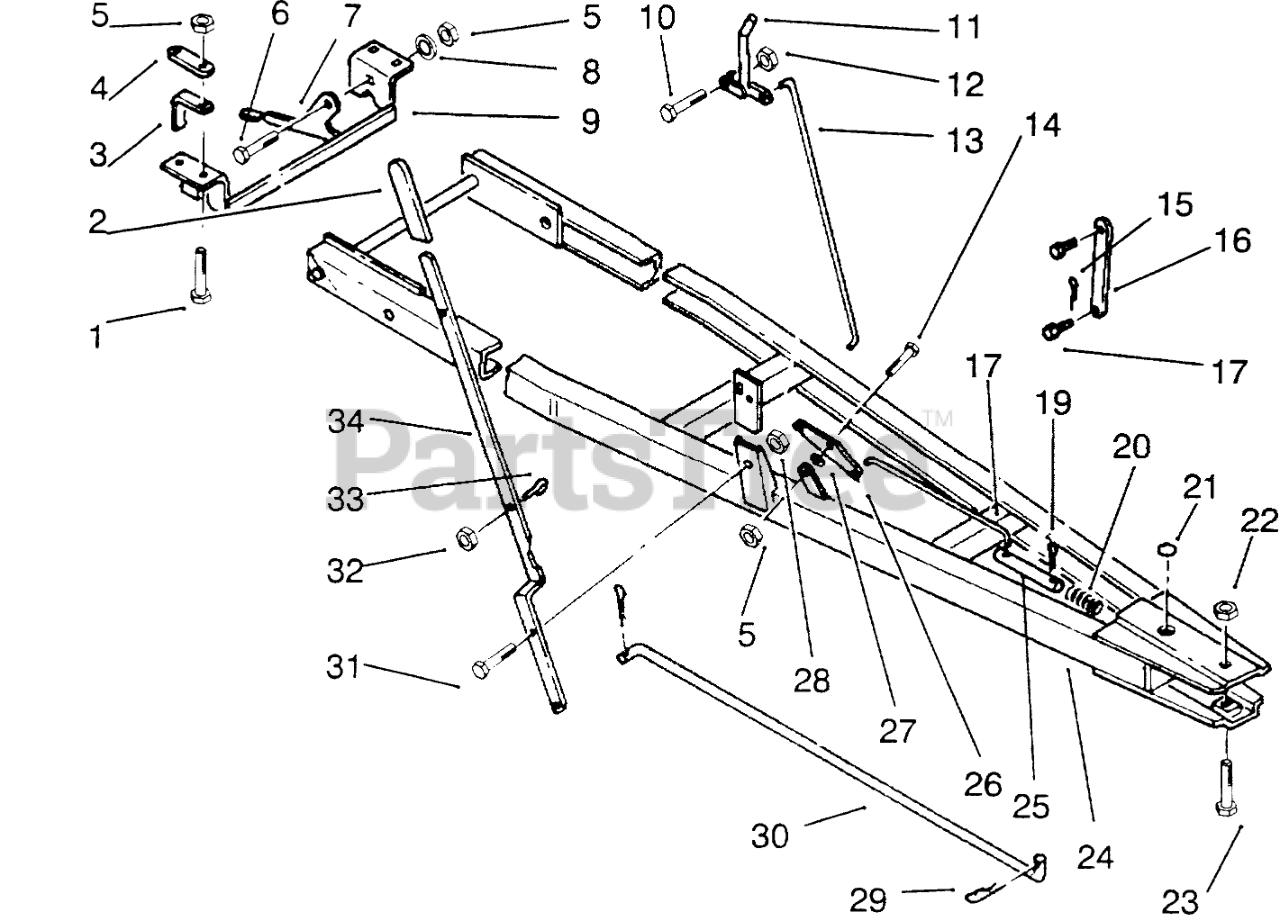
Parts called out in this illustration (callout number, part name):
1	SCREW-CARR
2	GRIP
3	SPACER-BRACKET
4	BRACKET-REAR LINK MOUNTING
5	NUT-LOCK, NI
6	SCREW-HH
7	PLATE-LATCHING
8	WASHER-FLAT
9	Bracket
10	SCREW-HH
11	INDEX LEVER
12	NUT-LOCK
13	UPPER INDEX ROD
14	SCREW-HH
15	PIN-HAIR
16	LINK-LIFT
17	CLEVIS PIN
18	Head-Cylinder
19	PIN-COTTER
20	SPRING-COMPRESSION
21	PLUG
22	NUT-LOCK
23	SCREW-HH
24	Frame Assembly (Incl. Ref. # 19, 20 & 25 )
25	Index Pin
26	Index Plate
27	WASHER-FLAT
28	Nut-Jam
29	PIN-HAIR
31	SCREW-HH
32	Nut
33	EYEBOLT
34	Index Lever
